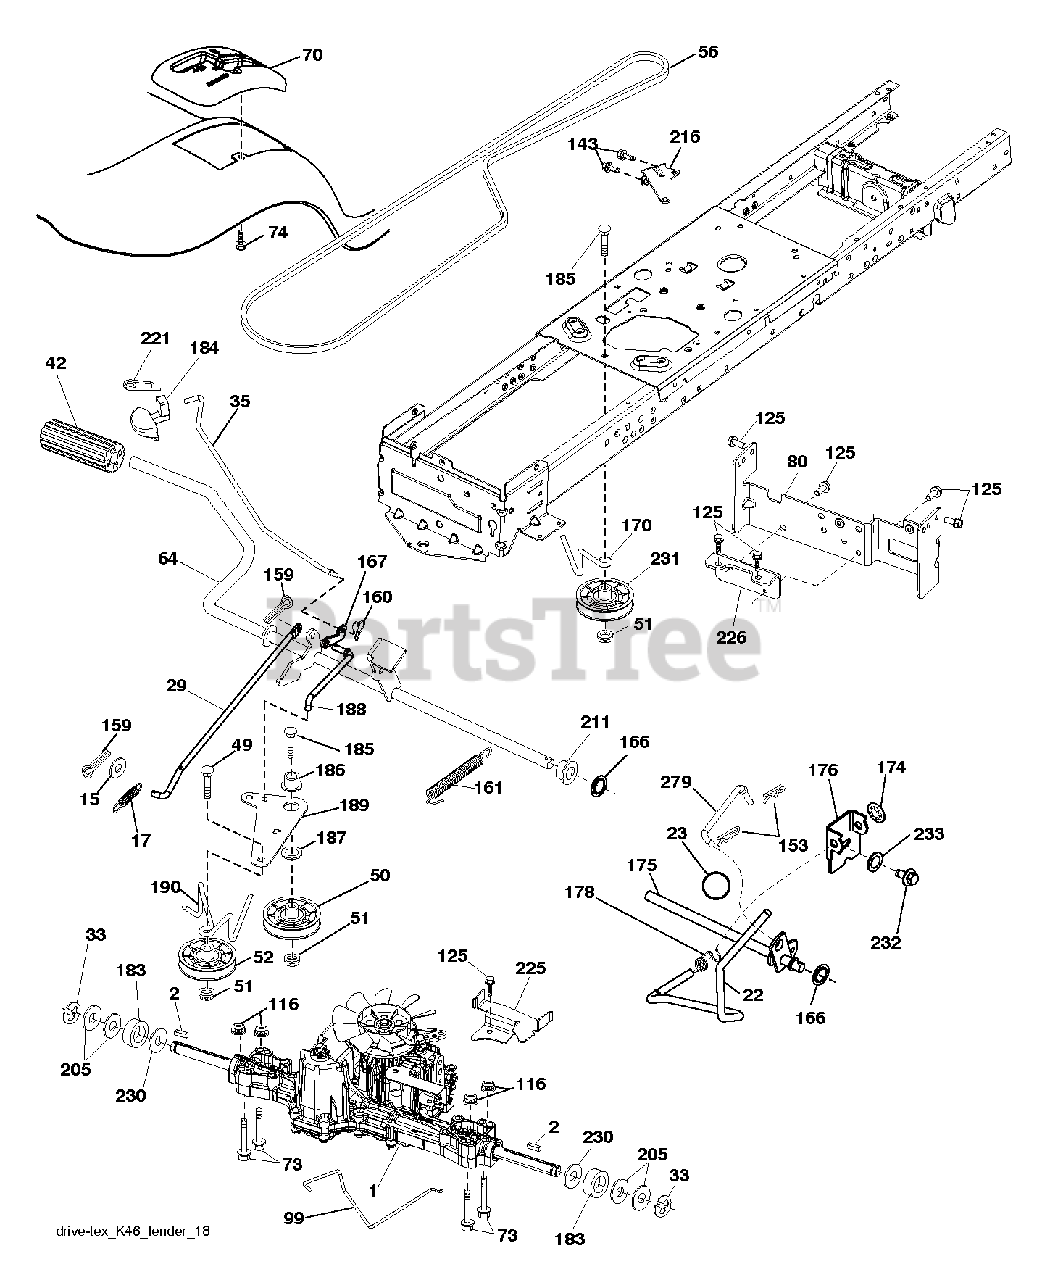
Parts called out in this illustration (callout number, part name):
2	SQUARE KEY
15	WASHER
17	SPRING.BRAKE.K46.GREEN
23	KNOB.DELUXE.(PISTOL.GRIP).BLAC
29	ROD.BRAKE.K46
35	ROD.BRAKE.PARKING.GT.H
42	PEDAL COVER T
50	IDLER.FLAT.910.OFFSET
51	NUT LOCK FLG 3/8-16 UNC
52	IDLER.V-GROOVE.910.OFFSET
56	V-BELT.MOWER.92.40.42/K46
64	SHAFT.ASM.PEDAL.BRAKE.
70	CONSOLE SHIFT
73	BOLT HEX 5/16-18 GR 5
74	SCREW.HI-LO.CONSOLE
80	STRAP TORQUE
99	ROD.SPRING.BYPASS.K46.LT.Z
116	NUT LOCK HEX FLANGE 5/16-18
125	SCREW
143	SCREW LT
153	RETAINER M
159	COTTER PIN
160	RETAINER CLIP
161	SPRING, RETURN LT
166	NUT.PUSH.625
167	LATCH.BRAKE.SPRING
170	KEEPER.CENTER SPAN.1.688
174	NUT.PUSH.500.2006
175	SHAFT.ASM.SHFT.T2.TLT
176	ARM.CLEVIS.ROD.SHIFT
178	SPRING.SHIFT.GT2006
183	SPACER AXLE
184	HANDLE.PARKG.BRK.HUSQ X667
186	SPACER.RETAINER
187	WASHER 12/32X2X10GA
188	RP LINK.CLUTCH.GROUND.DRIVE
189	BELLCRANK.GROUND.DRIVE.TEX.
190	KEEPER.BELLCRANK.DRIVE
211	BUSHING.SHAFT.BRAKE.HAND
216	BRACKET.PULLEY.IDLER.W/TEX
221	RETAINER.SPRING.CLIP.H
225	KEEPER.BELT.TRANSAXLE.K46
226	BRACKET.MOUNT.TORQUE.K46.TLT
230	WASHER.HARDENED
231	IDLER.V-GROOVE.1.688.OFFSET
232	BOLT FIN HEX 7/16-14 X 1
233	WASHER SERRATED
279	LINK.SHIFT.
